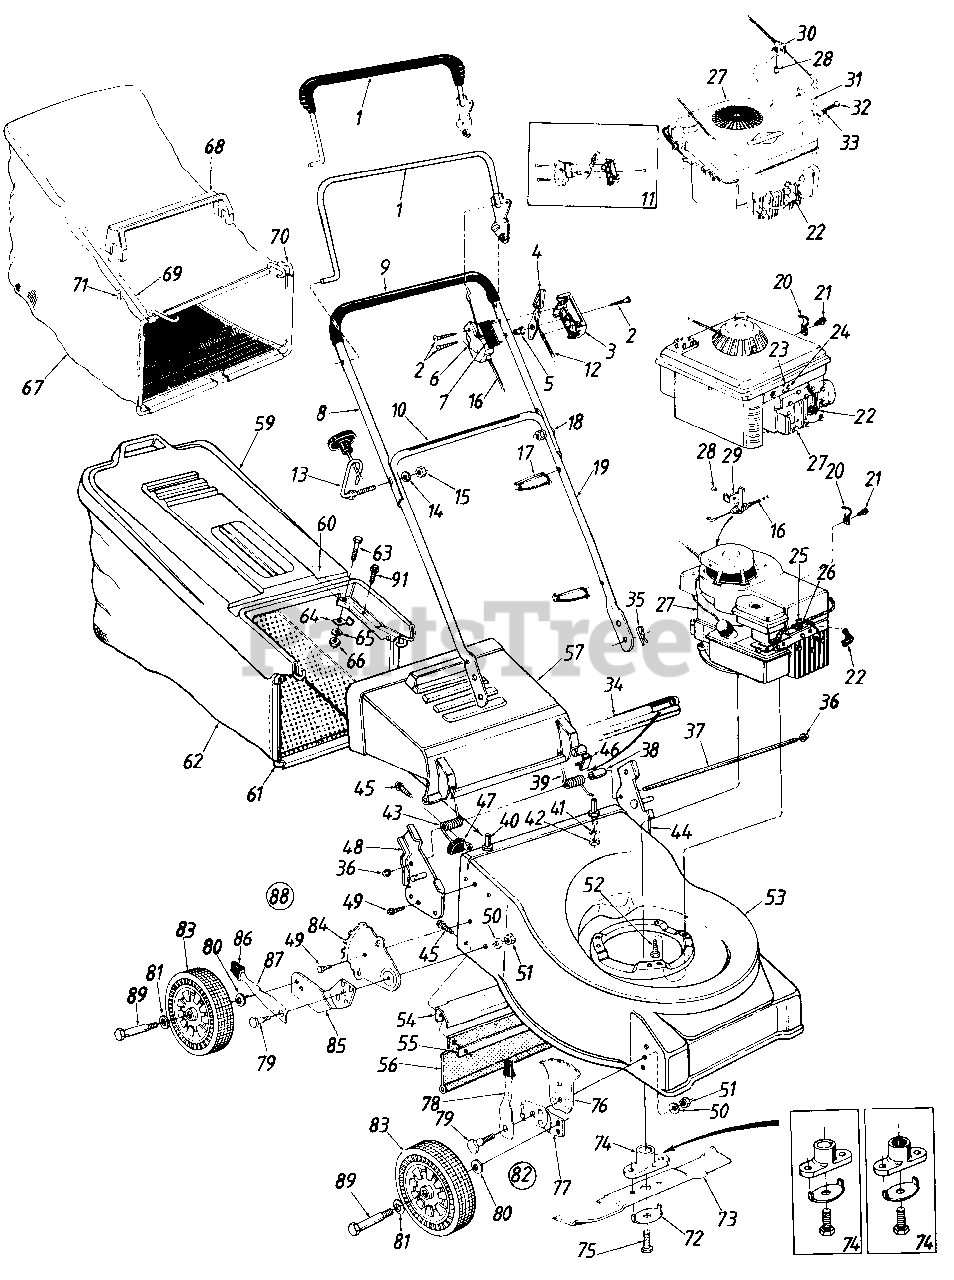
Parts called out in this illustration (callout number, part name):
1	Control Handle Ass'y.
2	Truss Mach. B-Tap Scr. #12 x 1.5" Lg.
3	Control Panel Half
4	Throttle Control Lever
5	Control Disc Pin
6	Clutch Panel Half
7	Control Label-Throttle
8	Upper Handle
10	Instruction Label-Handle
11	Control Housing Comp.
12	Throttle Wire-58" Lg.
13	Rope Guide Bolt
14	L-Wash. 5/16" I.D.
15	Hex Nut 5/16-18 Thd.
16	Control Cable-43" Lg.
17	Cable Tie
18	Curved Carriage Bolt 5/16-18 x 1.38" Lg.
19	Lower Handle
20	Cable Clamp
21	Hex B-Tap Scr. #10 x .38" Lg.
22	Spark Plug Boot
23	Cable Clamp
24	Hex B-Tap Scr. #10 x .62" Lg.
25	Cable Clamp
26	Hex AB-Tap Scr. #8 x .5" Lg.
27	Engine
28	Pop Rivet .156" Dia.
29	Cable Bracket
30	Cable Mtg. Brkt.
31	Mounting Brkt.
32	Truss Mach. Scr. #10 x .5" Lg.
33	L-Wash. #10 I.D.
34	Seal-Extrusion
35	Int. Cotter Pin 5/16" Dia.
36	Cap Speed Nut
37	Hinge Pin 17.75" Lg.
38	Spacer .255" I.D.
39	Torsion Spring-L.H.
40	Shld. Pin 3/8-24 x 1.43" Lg.
41	L-Wash. 3/8" I.D.*
42	Hex Jam Nut 3/8-24 Thd.
43	Torsion Spring-R.H.
44	Handle Brkt. Ass'y.-L.H.
45	Torx Mach. AB-Tap Scr. 1/4 x .62" Lg.
46	Deflector Plug
47	Corner Plug
48	Handle Brkt. Ass'y.-R.H.
49	Hex L-Wash. AB-Tap Scr. 1/4 x.62" Lg.
50	Bell-Wash. .39" I.D. x 1.38" O.D.
51	Hex Nut 3/8-16 Thd.*
52	Hex L-Wash. Hd. Scr. 3/8-16x 1" Lg.
57	Rear Chute Deflector
59	Hardtop Bag Cover
60	Rear Catcher Frame
61	Front Catcher Frame
62	Grass Bag
63	Truss Mach. Scr. 1/4-20 x 1" Lg.
64	Hardtop Mtg. Clip
65	Fl-Wash. .281" I D
66	Hex Nut 1/4-20 Thd.*
67	Grass Bag
68	Bag Handle
69	Rear Catcher Frame
70	Front Catcher Frame
71	Hex AB-Tap Scr. #12 x 1.25" Lg.
73	21" Blade
74	Blade Adapter Kit (Keyed)
75	Hex Bolt 3/8-24 x 1.5" Lg.
76	Height Adj. Plate
77	Pivot Bar
78	Spring Lever Ass'y. w/Knob
79	Shld. Bolt .50" Dia. x .357"
80	Bell-Wash. .38" I.D. x .88" O.D.
81	Fl-Wash. .531" I.D.
82	Height Adj. Ass'y. Comp.
83	Wheel Ass'y. Comp.
84	Index Plate
85	Pivot Bar-R.H.
86	Spring Lever Knob
87	Spring Lever
88	Rear Height Adj. Ass'y. Comp.-R.H.
89	Axle Bolt
91	Hex AB-Tap Scr. 1/4 x .62" Lg .
